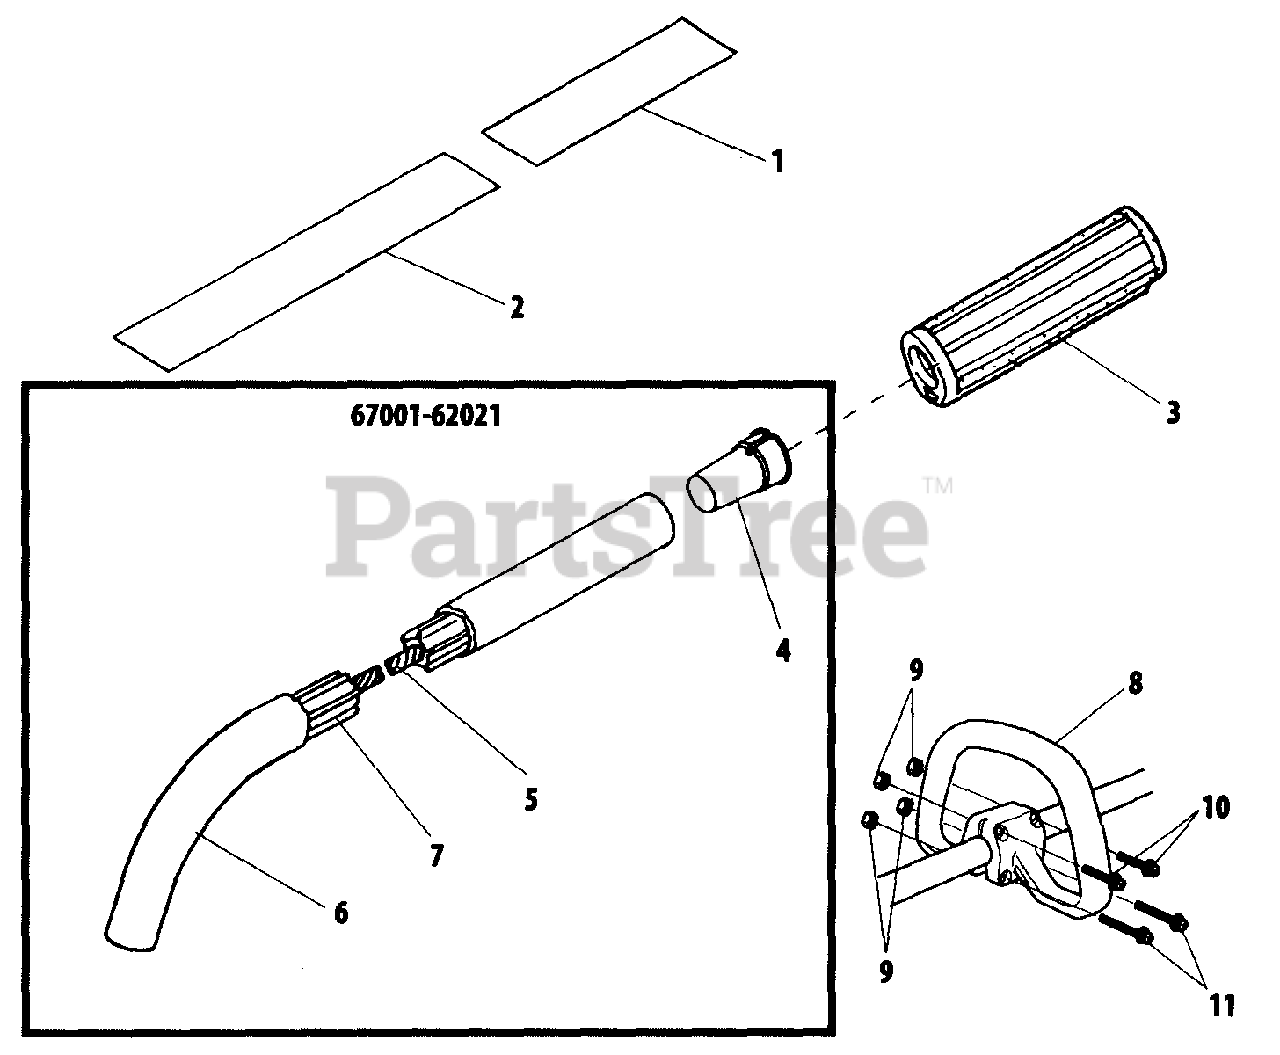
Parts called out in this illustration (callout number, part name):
1	LABEL - CAUTION
2	NAMEPLATE
3	GRIP
5	DRIVESHAFT - FLEXIBLE
6	PIPE, MAIN
7	LINER - FLEXIBLE
8	HANDLE - FRONT
10	SCREW - 5X30
11	SCREW - 5X45
67001-62021	MAIN PIPE ASSY
